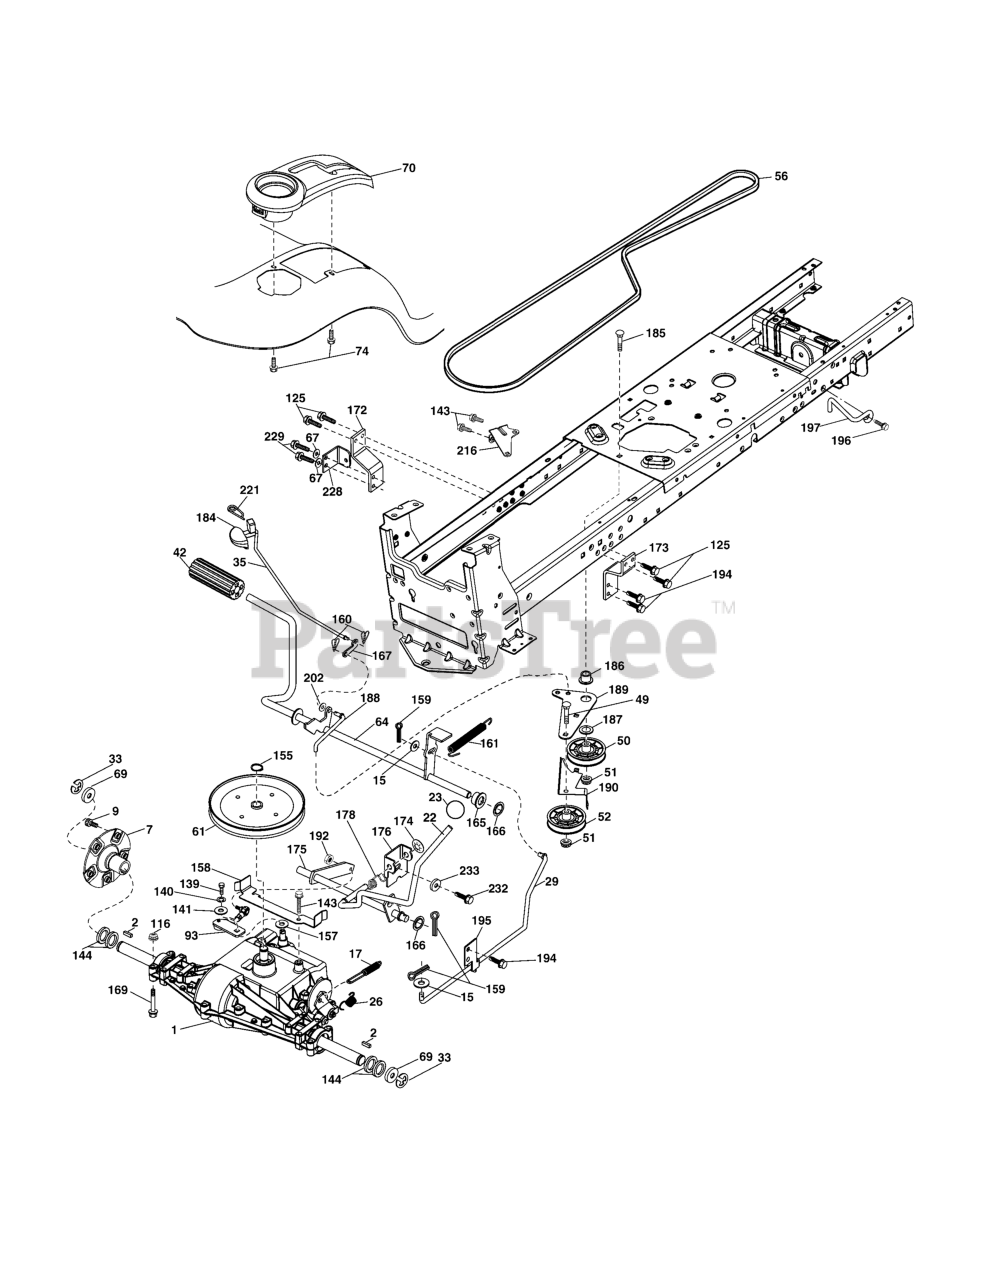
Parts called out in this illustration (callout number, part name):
2	Key 1/4 x 2.5
7	Hub Asm. Wheel Rear
9	Bolt Hub Wheel Rear
15	Washer 13/32 x 13/16 x 16 Ga.
17	Spring, Brake
22	Shift Shaft Asm.
26	Spring Brake Return
29	Rod, Brake
33	Ring E #5133-100
35	Rod, Brake, Park
42	Cover, Foot Pedal
49	Bolt
50	Pulley Idler Flat
51	Lock Nut 3/8-16
52	Idler V-Groove 910" Offset
56	V-Belt, Drive
61	Pulley Transaxle
64	Shaft Asm. Pedal Brake Control
67	Washer 13/32 x 13/16 x 12 Ga.
69	Washer
70	Console
74	Screw 1/4 x 1/2
93	Link Shift
116	Nut Lock Hex Flange 5/16-18
125	Screw 5/16-18 x 3/4
139	Bolt 1/4-28
140	Washer Lock Hvy Helical
141	Washer 9/32 x 3/4 x 10
143	Screw 5/16-18 x 1/2
144	Washer Spacer Axle
155	Ring Retainer
157	Washer Plate
158	Belt Keeper
159	Pin Cotter 1/8 x 3/4
160	Retainer Clip
161	Spring, Return, Clutch
165	Busing Shaft Brake Hand Control
166	Nut Push .625
167	Latch Brake Parking
169	Bolt 5/16-18 x Gr. 5
172	Strap Torque LH
173	Torque Strap RH
174	Nut Push
175	Shaft Asm. Shift Gear Drive
176	Arm Clevis Rod Shift
178	Spring Shift
184	Handle Parking Brake
185	Bolt
186	Spacer Retainer
187	Washer
188	Link Clutch Ground Drive
189	Bellcrank Ground Drive
190	Keeper Bellcrank Ground Drive
192	Nut Lock Center 1/4-28
194	Screw 5/16-18 x 3/4
195	Bracket Brake Rod
196	Screw 3/8-16 x 1
197	Bracket Anti-Rotation Clutch
202	Washer
216	Bracket Pulley Idler
221	Retainer Spring Clip Handle
228	Bracket Anti-Sway
229	Screw 5/16-18 x 1
232	Bolt 7/16-14 x 1 Gr. 5
233	Washer Serrated
